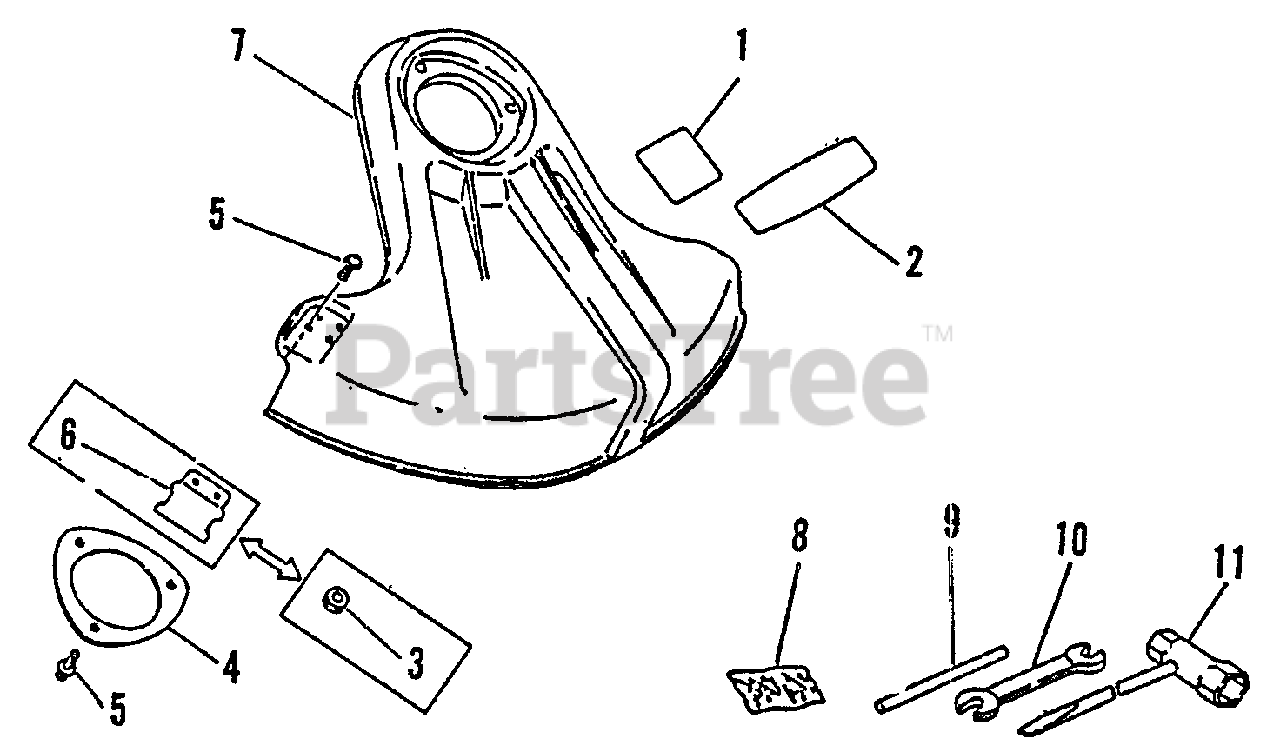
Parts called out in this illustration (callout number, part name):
1	LABEL, CAUTION
2	LABEL
3	NUT M5
4	PLATE, SHIELD Ø49.5 MM
5	SCREW 5×16
6	CUTTER, LINE
7	SHIELD ASSY
8	PIN, COTTER 2×22 (PKG. OF 10)
9	TOOL, LOCKING 5×120 MM
10	SPANNER 8×10
11	T-WRENCH 17x-19 L200
